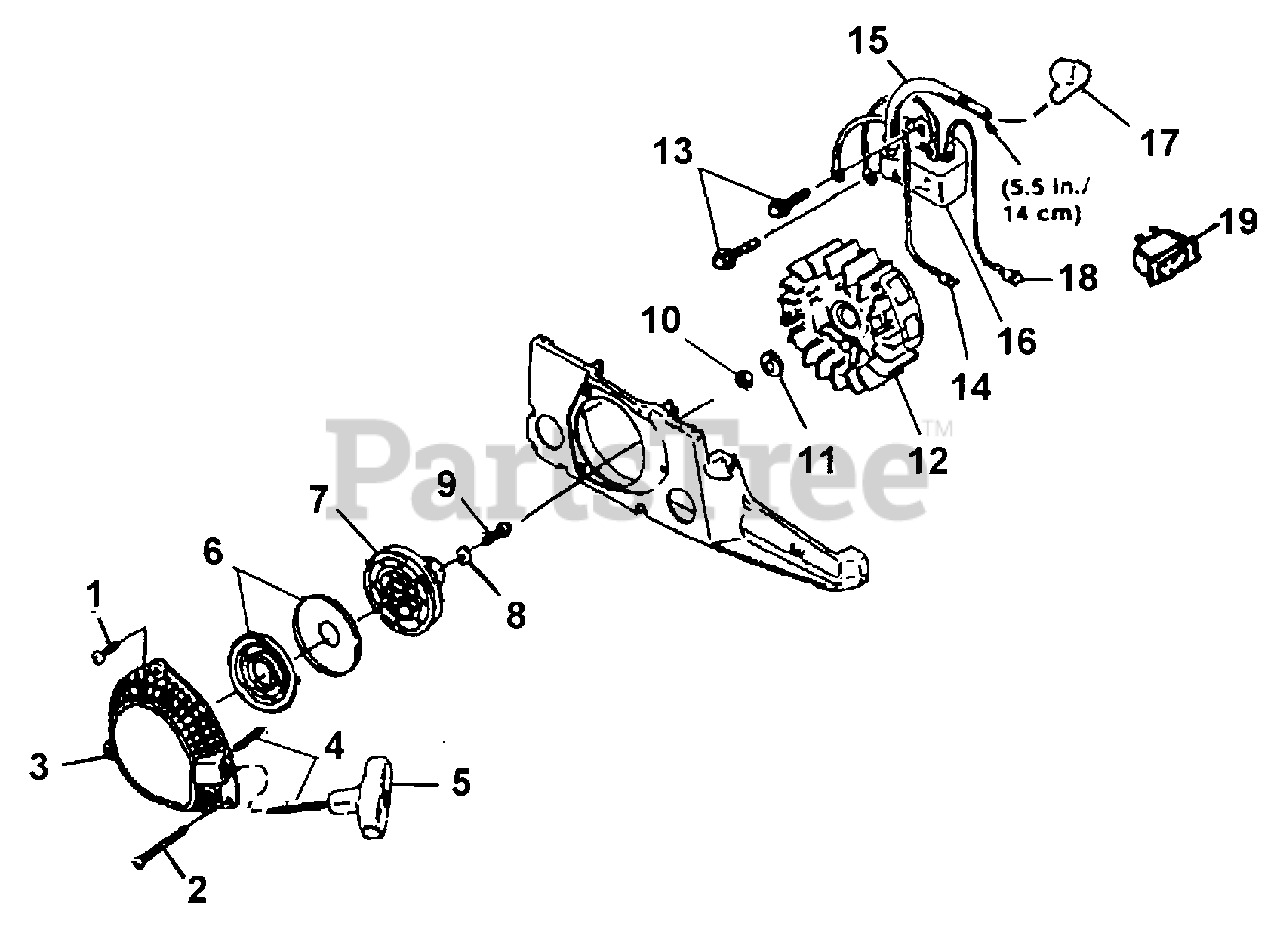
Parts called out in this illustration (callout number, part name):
1	SCREW-Thread Form (8-16 x 5/8")
2	SCREW Thread Form (8-16 x 2 1 /4)
3	STARTER - COMPLETE
4	ROPE, STARTER (46")
5	GRIP STARTER
6	SPRING & CONTAINER
7	PULLEY
9	SCREW Plastite (10-14 x 5/8")
10	NUT, JAM
11	WASHER LOCK (3/8)
12	ROTOR & STARTER PAWLS
13	SCREW, Sems Hex Hd. (10-24 x 7/8"
14	IGNITION GROUND WIRE
15	SLEEVE, Insulating
16	IGNITION MODULE
17	SPARK PLUG BOOT KIT
18	IGNITION WIRE
19	SWITCH
